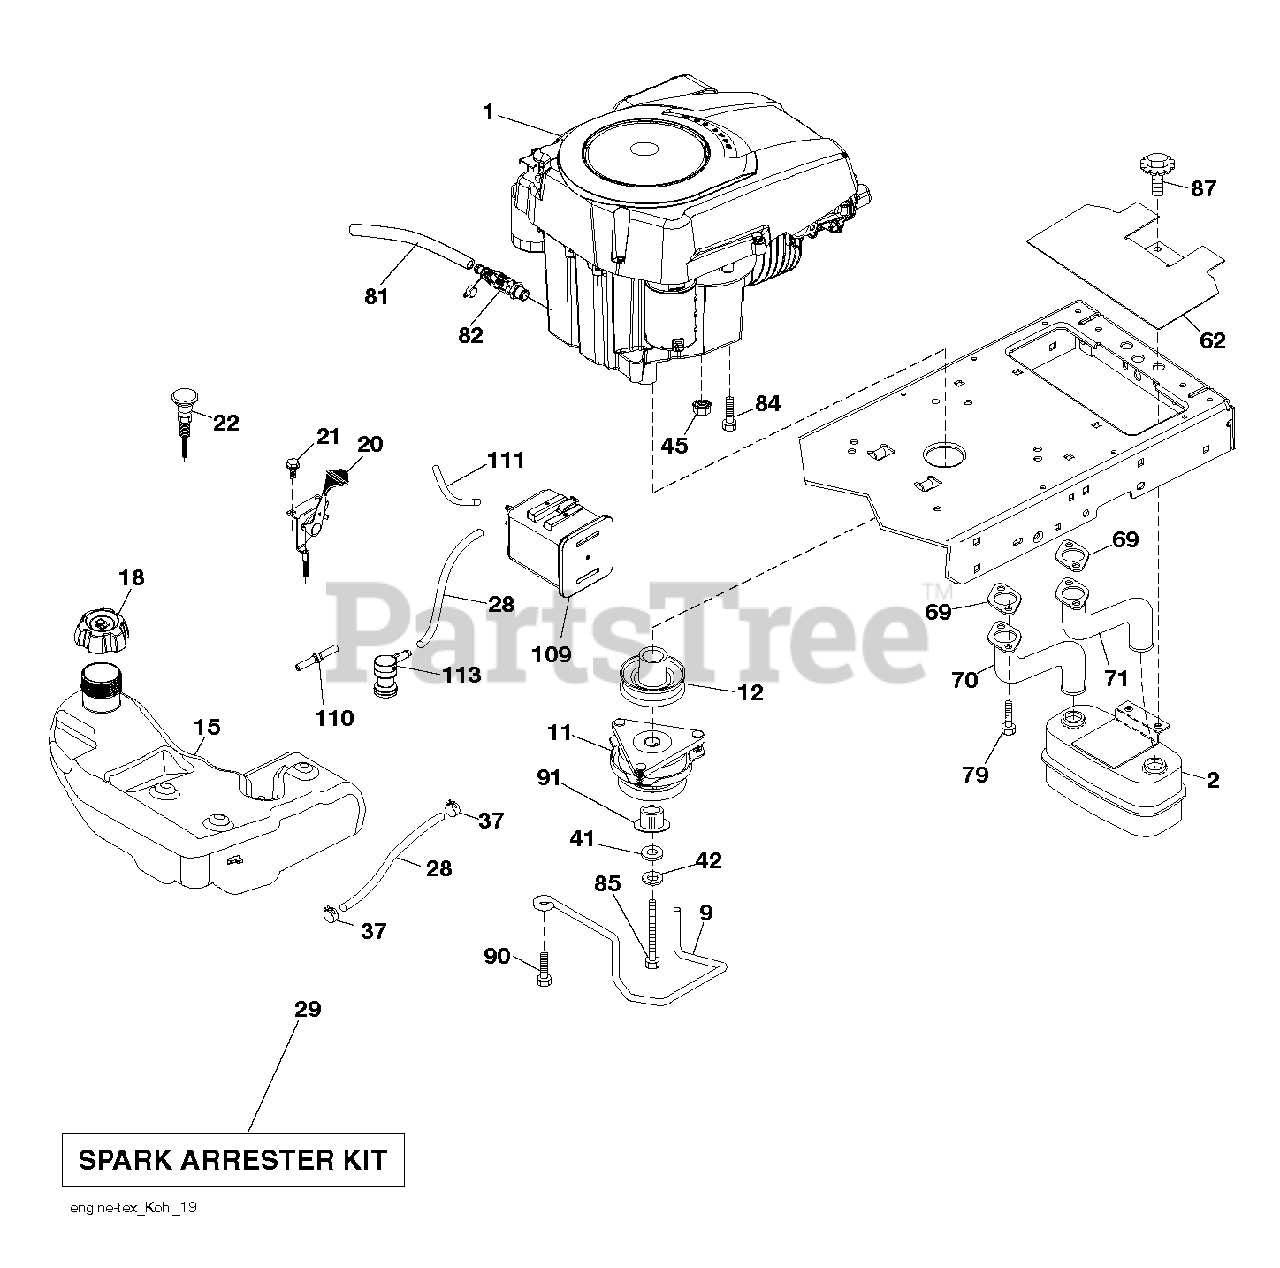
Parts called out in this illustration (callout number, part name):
2	MUFFLER.TWIN.CYL.LOW.TONE
9	KEEPER.BELT.ENGINE.4.2
11	CLUTCH MZ ZTR GT.48/54"1.125"
12	PULLEY ENGINE
15	RP TANK.ASM.FUEL.4GA.CARB
18	CAP.ASM.FL.RITCH.3"E10.SYM.498
20	THROTTLE CONTROL
21	SCREW.#10 X 0.750.BOS
22	CONTROL.CHOKE.ERGO.PUSH-IN.BLA
28	LINE.FUEL.64"REAR.EMIS
29	KIT.SPARK ARRESTOR 794945 B&S
37	HOSE CLAMP
42	LOCKWASHER
45	NUT
62	SHIELD.HEAT.MUFFLER
69	GASKET.EXHAUST.KOHL.CV18-CV26
70	RP.PIPE-EXHAUST LH
71	RP.PIPE-EXHAUST RH
79	SCREW.SOCKET HD.5/16-1
81	TUBE, DRAIN OIL ASM.
82	VALUE.OIL.DRAIN
84	SCREW 3/8-16X1
85	BOLT HEX 7/16-20 X 3.75 GR. 5
87	BOLT.5/16-18UNCX1.W/SEMS.BLK
90	SCREW 3/8-16X1
91	BUSHING.1.375OD
109	CANNISTER, CARBON
110	VALVE.ASM.ANTI-SLOSH
111	PURGE.LINE.36"REAR.CALIFORNIA
113	VALVE.SLANT.CARTRDG.90 DEG.TEX
